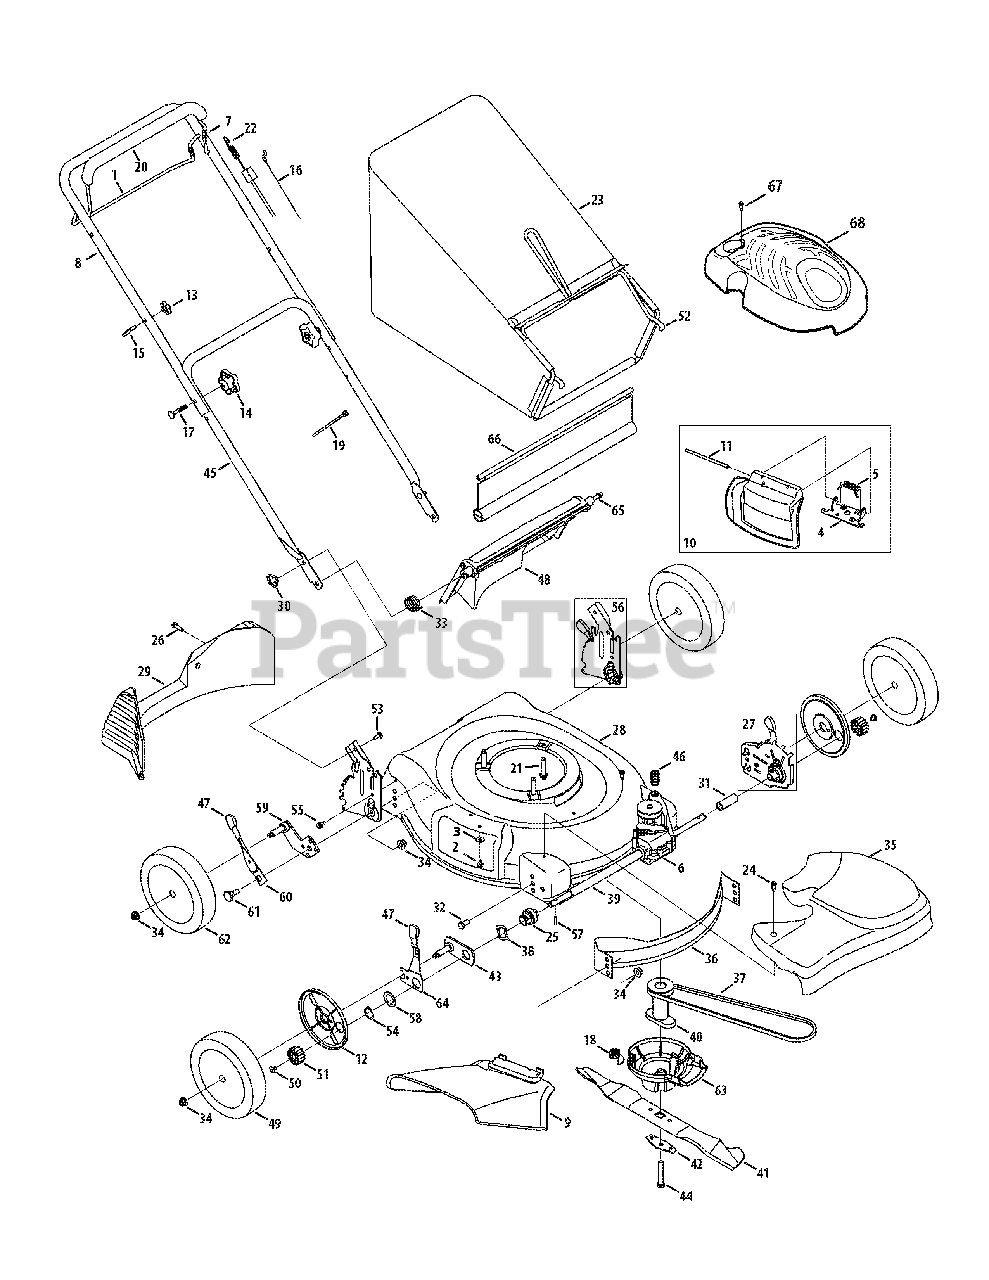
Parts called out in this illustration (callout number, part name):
1	Drive Control
2	TT Screw 1/4-20 x 0.5
3	Bell Washer.265 x 0.75
4	Deflector Chute Adapter
5	Torsion Spring
6	Transmission Assembly
7	Blade Control
8	Upper Handle
9	Chute Deflector
10	Mulch Plug Complete
11	Hinge Pin
12	Wheel Dust Cap
13	Handle Knob
14	Star Knob
15	Eye Bolt
16	Control Cable
17	Carriage Bolt 5/16-18 x 2.0
18	Engine Baffle Bracket
19	Cable Tie
20	Bail Cover
21	Self-Tapping Sems Screw
22	Drive Cable - 51"
23	Grass bag
24	Shoulder Screw # 12 -24
25	Front Bearing Assembly
26	Screw, 1/4-15 x 1.000
27	Height Adjustment Ass’y - RH
29	Rear Baffle
30	Wing Nut
31	Slev. Spacer 1.4" Lg.
32	Hex Screw, 3/8-16 x.75
33	Torsion Spring - RH
34	Flange Lock Nut, 3/8-16
35	Transmission Cover - Black
36	Front Baffle
37	V-Belt
38	Wave Washer
39	Sleeve Spacer 8.985" Lg.
40	Blade Adapter, One Piece
41	21" Mulching Blade
42	Blade Bell Support
43	Pivot Plate Assembly
44	Hex Screw 3/8-24 x 2.50
45	Lower Handle
46	Belt Tension Spring
47	Adjustment Knob
48	Rear Discharge Door
49	Front Wheel
50	Screw, 1/4-20 x .390
51	Gear 14T RH FWD
53	Carriage Bolt 1/4-20
54	Snap Ring
55	TT Scr. w/Washer 1/4-20 x.625
56	Handle Bracket Assembly - RH
57	Dowel Pin
58	Washer
59	Pivot Arm Assembly - RH
60	Rear Spring Lever
61	Shoulder Scr.500 Dia. x.434
62	Rear Wheel
63	Engine Baffle
64	Front Lever - RH
65	Pivot Rod
66	Rear Trailing Shield
67	Screw, HL, #12-16 x 1.00
68	Engine Shroud
